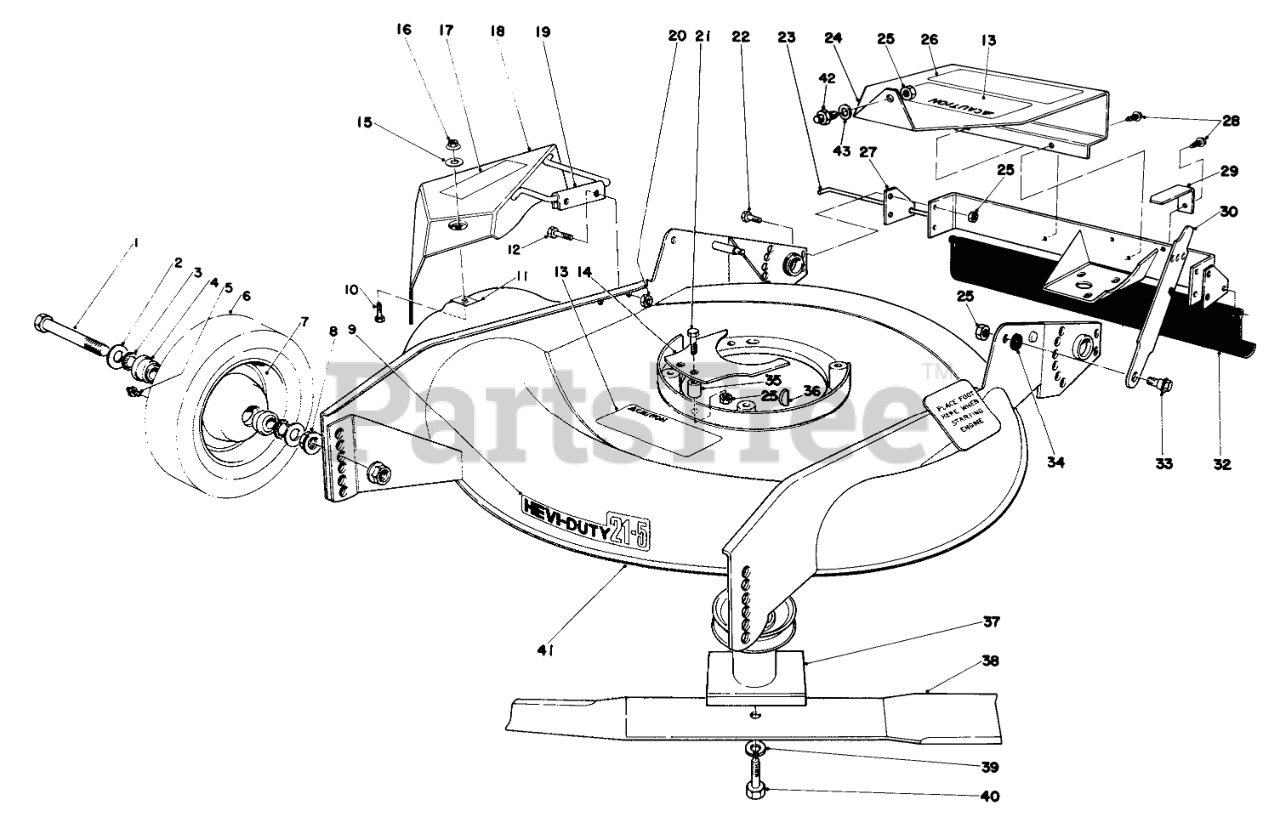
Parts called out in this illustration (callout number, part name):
1	SCREW-HH
2	WASHER-FLAT
3	FELT WASHER
4	BEARING-BALL
5	FITTING-GREASE
7	Wheel & Tire Assembly (Incl. Ref. #4-6)
8	NUT-HF
9	Decal-Hevi-Duty 21-5
10	SCREW-HH
11	NUT-SPEED
12	SCREW-HH
13	DECAL SAF INST
14	Belt Guide-Front
15	WASHER-FLAT
16	NUT-LOCK, HHF
17	Decal-Deflector
18	Deflector
19	Hinge-U Bracket
20	NUT-LOCK
21	SCREW-HH
22	SCREW-HH
23	SAFETY SHIELD ROD
24	Shroud
25	Nut
26	Decal
27	Bracket-Safety Shield
28	Screw
29	Belt Guide-Rear
30	Latch
32	Rear Safety Shield
33	SCREW-SHOULDER
34	SPACER
35	BELT GUIDE SPACER
36	KEY-WOODRUFF
37	Yoke Bushing
38	BLADE
39	WASHER-LOCK
40	Place Bolt
41	Housing
42	Head Bolt Stud
43	Washer
